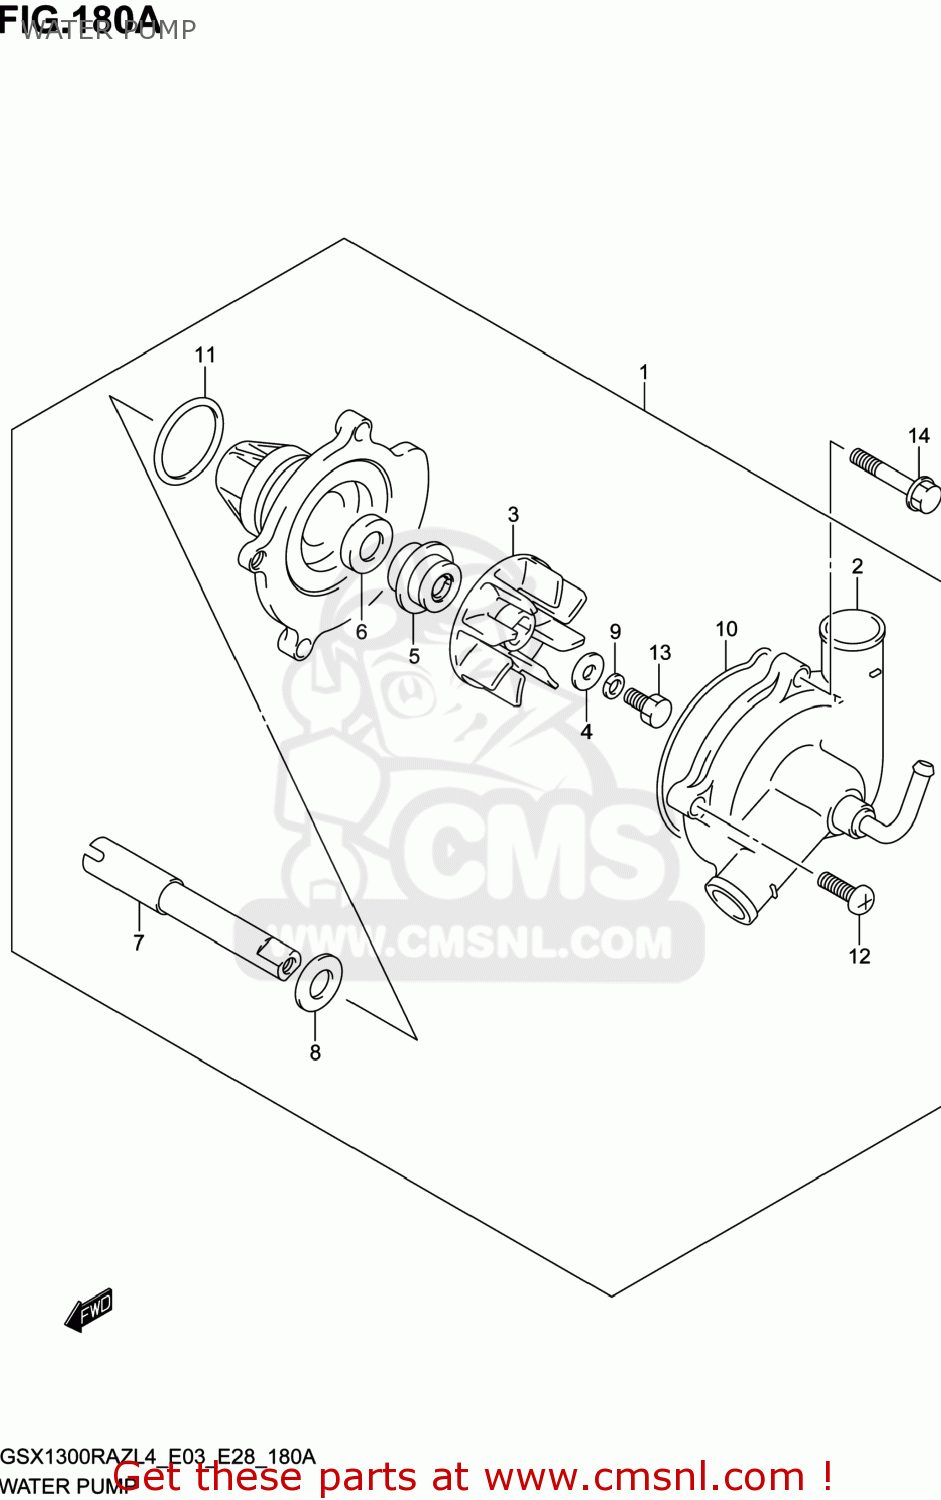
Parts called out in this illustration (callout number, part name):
1	PUMP ASSY,WATER
2	CASE
3	IMPELLER
4	GASKET(6X15X2.2) (NAS)
5	SEAL,MECHANICAL
6	SEAL,OIL
7	SHAFT
8	WASHER
9	WASHER
10	O RING
11	O RING,WATER PUMP HOLDER
12	SCREW
13	BOLT(6X13)
14	BOLT
